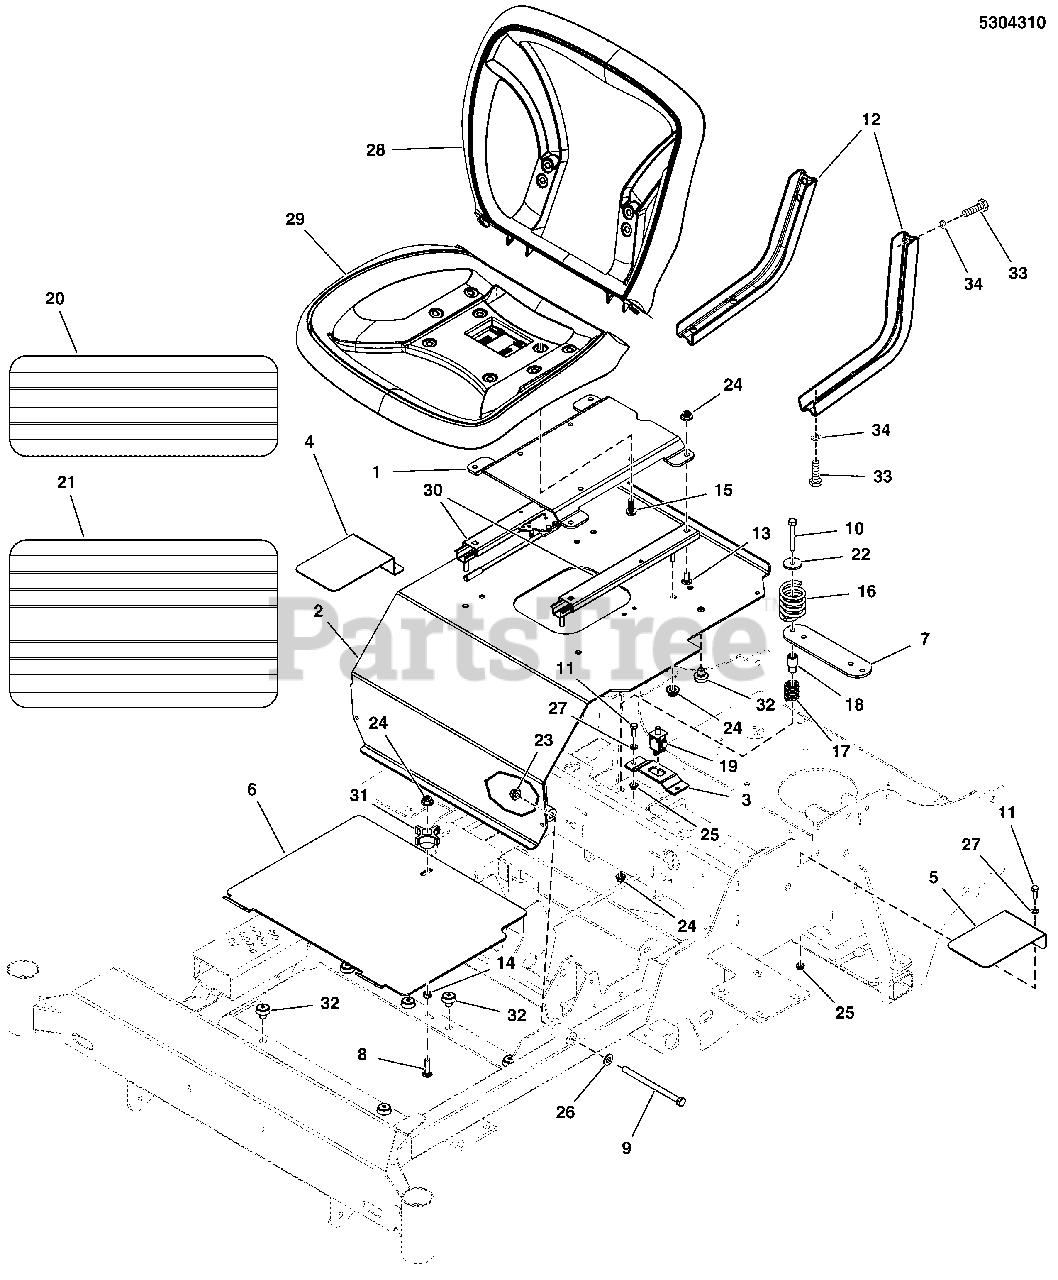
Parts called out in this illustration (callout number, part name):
1	PLATE, SEAT MOUNT - CONTENDER
2	ASSM, SEAT PLATE W/DECALS, CNTDR-DOM
3	PLATE, SEAT SWITCH - ORG
4	PLATE, FAN GUARD, RH - BLK
5	PLATE, FAN GUARD, LH - BLK
6	PLATE, FLOOR, REMOVABLE - ORG
7	PLATE, SEAT SWITCH - ORG
8	BOLT, 5/16-18 X 1-1/4, CARRIAGE CZ
9	BOLT, 3/8-16 X 5-1/2 GD5 CZ
10	BOLT, 5/16-18 X 2-1/4 GD5 CZ
11	BOLT, 1/4-20 X 3/4 GD5 CZ
12	SUPPORT, MESH SEAT (BLACK)
13	RHSSNB,5/16-18 X 3/4 GR5 ZINC/CLEAR
14	NUT, 5/16-18, HEX, CNTR LK,ZINC PHOS/OIL
15	SCREW, 5/16-18x0.750, GR5, WHIZ-LOCK, ZC
16	SPRING, SEAT SUPPORT
17	SPRING COMP .76IDX1.3LGX.105WIRE BLACK
18	SPACER, .33 X .66 X 1.31 SHLDR, CZ
19	SWITCH, PLUNGER, NO, SINGLE POLE SNAP-IN
20	SAFETY WALK, FLOOR REST, 6.00 X 16.00
21	SAFETY WALK, FLOOR PLATE, S50X, 10X16
22	WASHER, .34 X 1.25 X 10 GA
23	NUT, 3/8-16 HEX NYLOCK FLANGE
24	NUT, 5/16-18 HEX NYLOCK FLANGE
25	NUT, 1/4-20 HEX NYLOCK FLANGE
26	WASHER, 3/8 SAE
27	WASHER, 1/4 SAE
28	SEAT, MESH BACK
29	SEAT, MESH BOTTOM
30	SLIDE-SEAT VIPER (2 PC SEAT)
31	KNOB-INT THR .312-18 4-ARM 2.12WD 1.06LG
32	MNT, VBRTN, RBBR
33	SCREW, 5/16-18X.750 BUTTON HD PHOS&OIL
34	WASHER, 5/16 LOCK CZ
